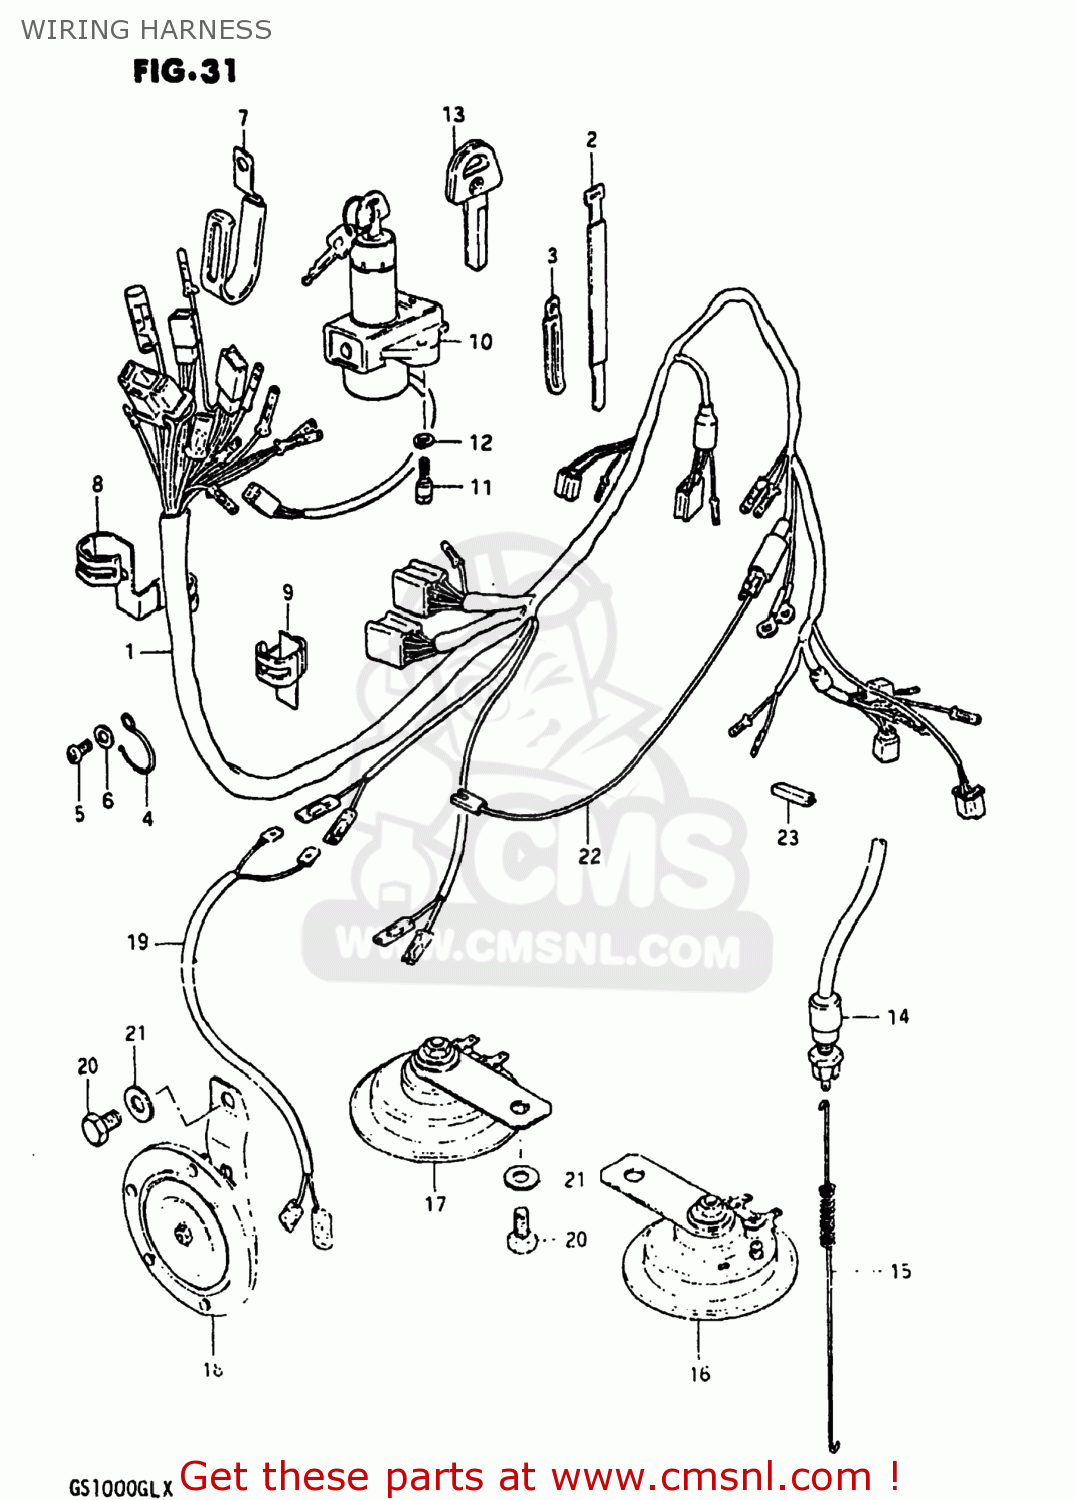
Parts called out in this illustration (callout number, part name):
1	HARNESS,WIRING
2	CLAMP
3	CLAMP
4	GUIDE,WIRING HARNESS
5	SCREW 6X12
6	WASHER
7	CLAMP,WIRING HARNESS
8	CLAMP,WIRING HARNESS
9	CLAMP,WIRING HARNESS
10	SWITCH ASSY,IGNITION
11	BOLT
12	LOCK WASHER
13	KEY,BLANK
14	SWITCH ASSEMBLY,STOP LAMP
15	SPRING
16	HORN ASSEMBLY,LOW PITCH
17	HORN ASSEMBLY,HIGH PITCH
18	HORN ASSEMBLY
19	WIRE
20	BOLT 8X12
21	WASHER
22	WIRE
23	PROTECTOR,WIRING HARNESS
